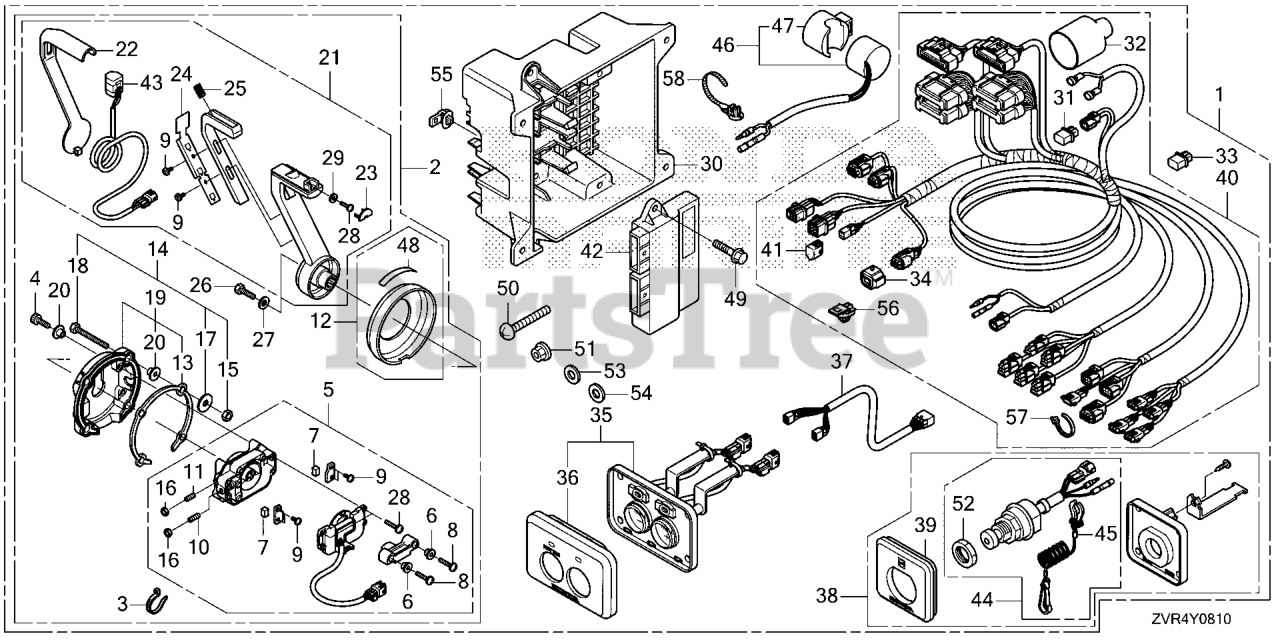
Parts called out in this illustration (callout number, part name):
1	BOX KIT, R/C (2ND)
2	BOX ASSY., REMOTE CONTROL (FLUSH MOUNT)(RH)
3	BAND, NYLON
4	BOLT, SOCKET
5	HOUSING ASSY. (FLUSH MOUNT)
6	COLLAR, STOPPER
7	SHOE, BRAKE
8	SCREW
9	SCREW
10	SCREW SET
11	SCREW SET
12	COVER ASSY. (FLUSH MOUNT)
13	SHEET, WATERPROOF (FLUSH MOUNT)
14	NUT SET, MOUNTING
15	NUT, NYLON
16	NUT
17	WASHER
18	BOLT
19	BASE ASSY. (FLUSH MOUNT)
20	COLLAR, BASE
21	LEVER ASSY. (FLUSH MOUNT)
22	PANEL, LEVER (FLUSH MOUNT)
23	CAP, LEVER (FLUSH MOUNT)
24	PLATE, LEVER PANEL
25	SPRING, COIL
26	BOLT
27	WASHER
28	SCREW
29	WASHER
30	CASE, CONTROL UNIT
31	TERMINATOR ASSY.
32	COVER, CONNECTOR (NOT AVAILABLE)
33	DUMMY, WATERPROOF CONNECTOR
34	SUSPENSION, CONNECTOR
35	PANEL ASSY., FUNCTION SWITCH
36	PANEL, FUNCTION SWITCH
37	SUB-HARNESS ASSY., FUNCTION SWITCH
38	PANEL ASSY., EMERGENCY STOP
39	PANEL, EMERGENCY STOP SWITCH
40	CABLE ASSY., REMOTE CONTROL (2ND)
41	CAP, DUMMY (WPC 4P 090 M) (RED)
42	UNIT ASSY., CONTL
43	SWITCH ASSY., POWER TRIM-TILT (FLUSH MOUNT)
44	SWITCH ASSY., EMERGENCY STOP
45	WIRE, EMERGENCY
46	BUZZER ASSY., WARNING
47	SUSPENSION, WARNING BUZZER
48	MARK, FLUSH MOUNT
49	BOLT, FLANGE (6X20)
50	SCREW, PAN (5X40) DUAL QTY = (8) (SINGLE)
51	NUT, FLANGE (5MM)
52	NUT
53	WASHER, PLAIN (5MM)
54	WASHER, SPG (5MM)
55	CLIP, CONNECTOR (DARK BLUE)
56	CLIP, CONNECTOR (DARK BROWN)
57	CLIP, HARNESS BAND (145MM) (BLACK)
58	CLIP, BAND HARNESS (152.4MM) (BLACK)
